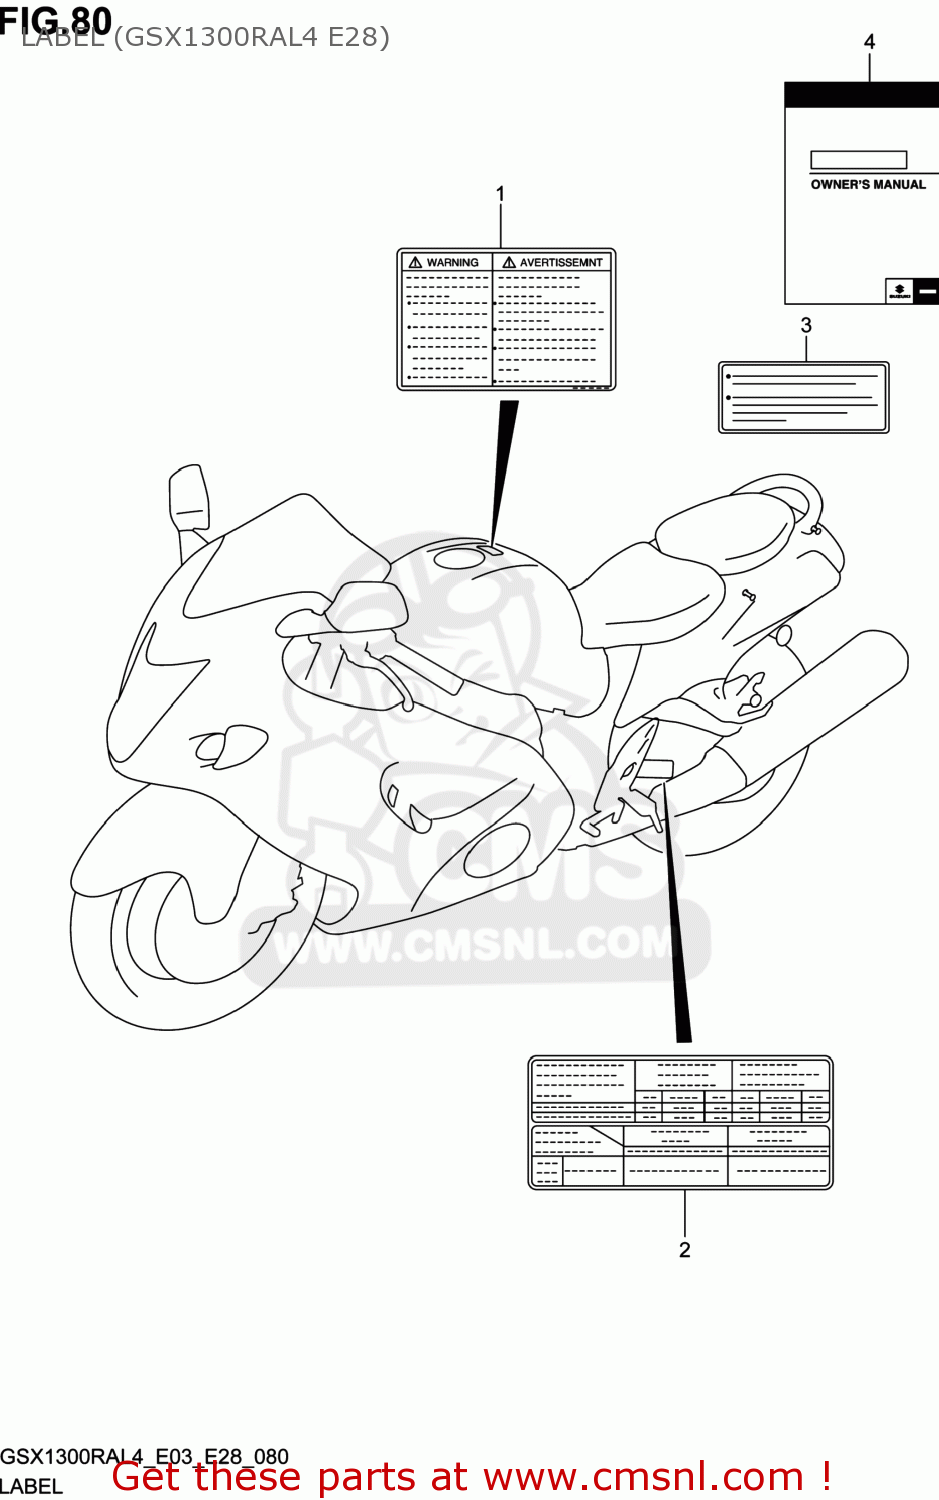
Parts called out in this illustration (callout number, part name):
1	LABEL,GENERAL WARNING
2	LABEL,TIRE INFORMATION
3	LABEL,FUEL INFORMATION
4	MANUAL,OWNER'S
